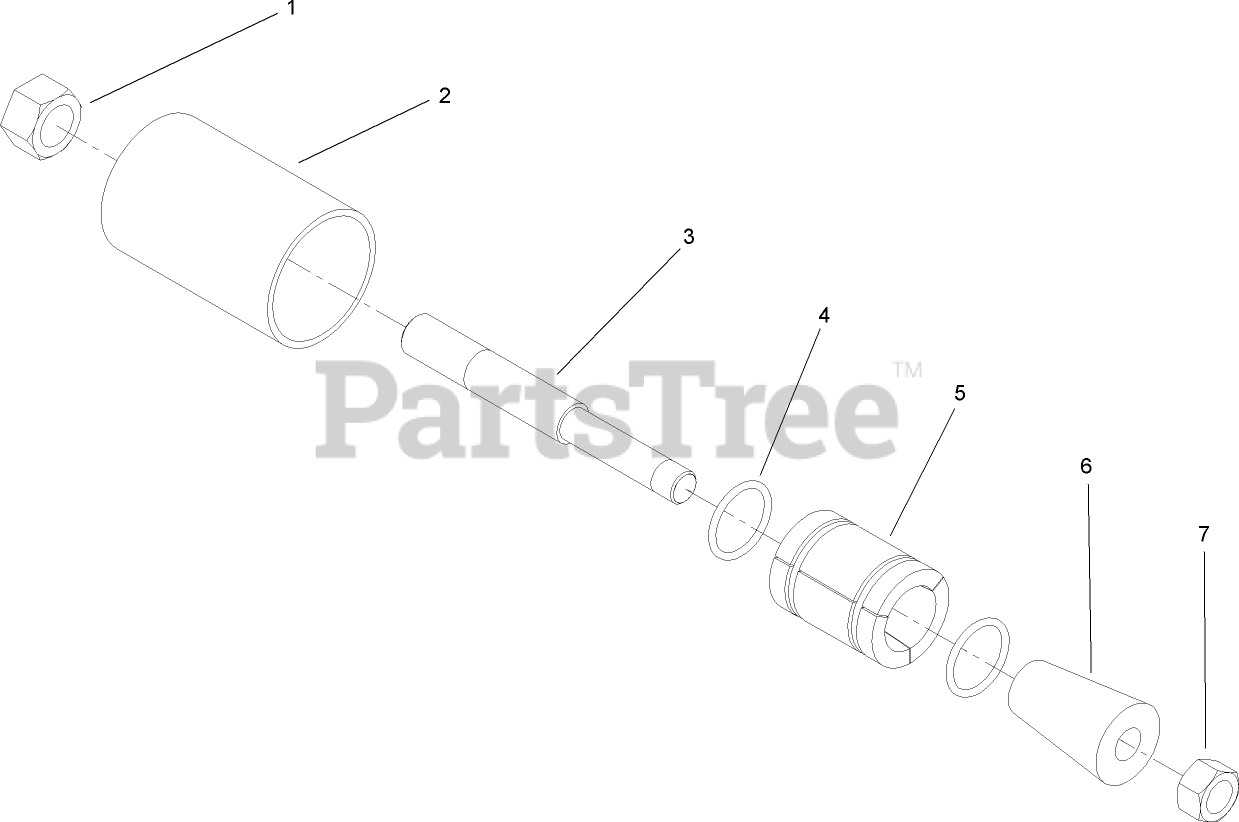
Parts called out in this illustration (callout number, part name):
1	NUT-HEX
2	ROD-PULLER
3	GRIP-OUTER
4	O-RING
5	GRIP-INNER
6	CONE-PULLER
7	NUT-HEX
